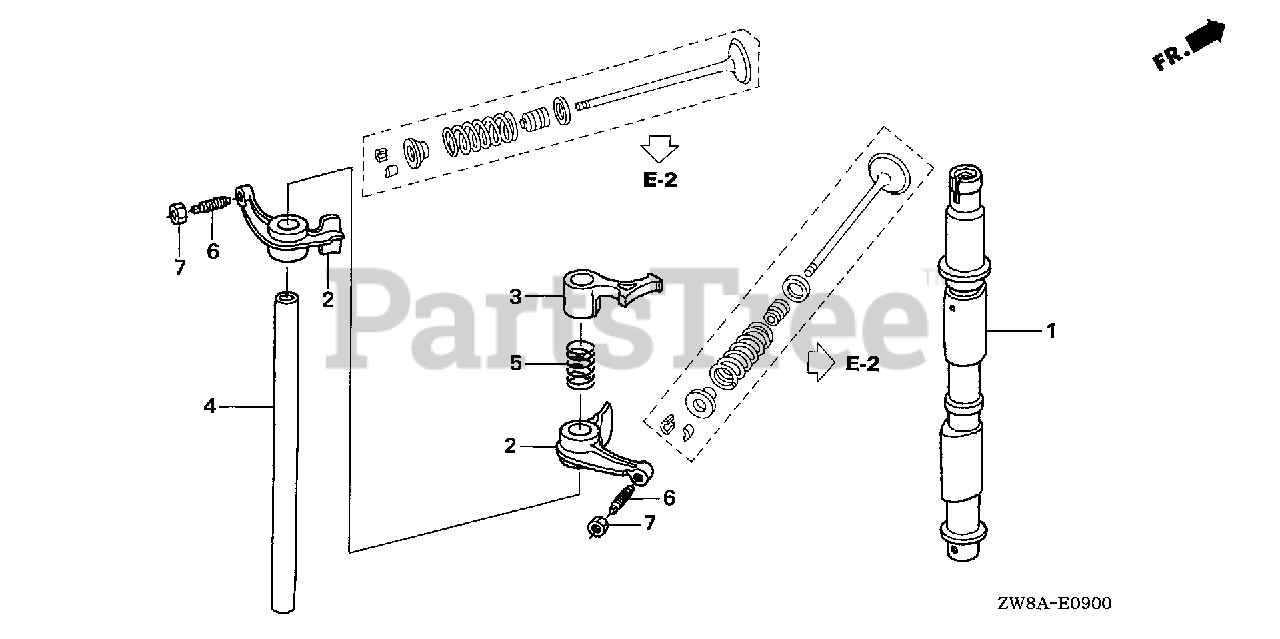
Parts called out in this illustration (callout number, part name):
2	ARM, VALVE ROCKER
3	ARM, FUEL PUMP ROCKER
4	SHAFT, ROCKER ARM
5	SPRING, ROCKER ARM
6	SCREW, TAPPET ADJUSTING
7	NUT, TAPPET ADJUSTING
